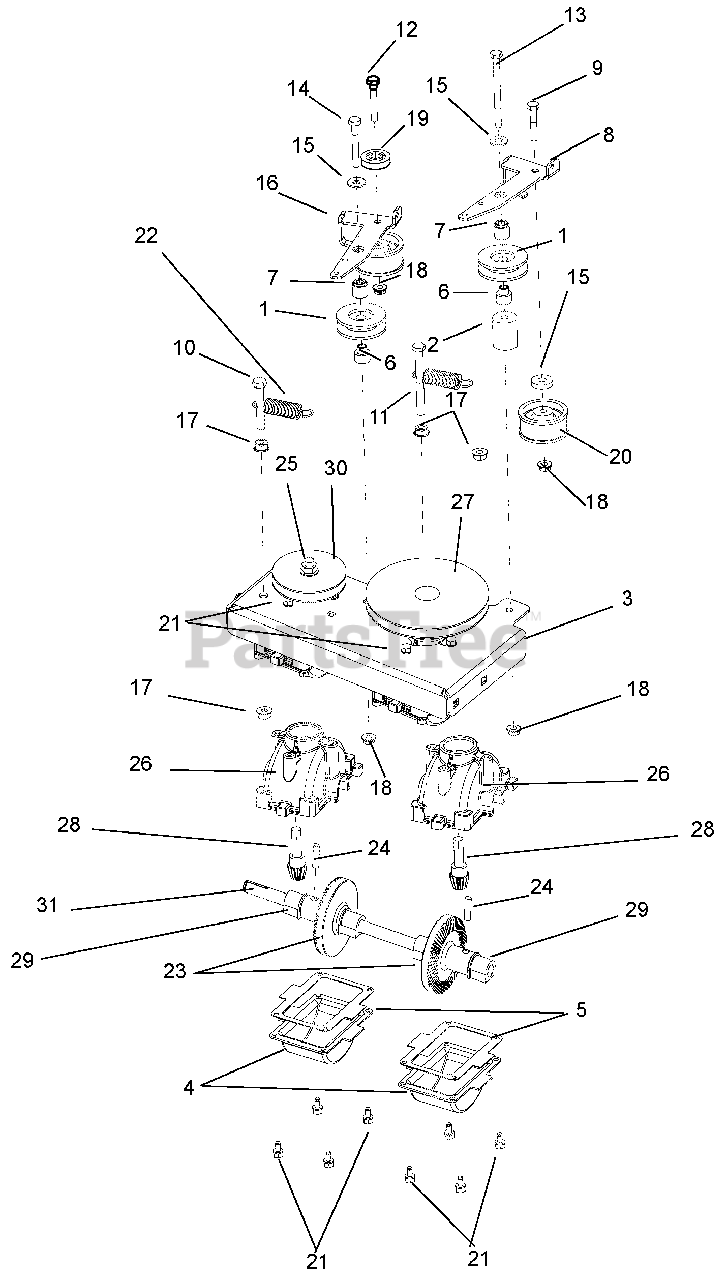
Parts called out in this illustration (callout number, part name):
1	IDLER, 3L FRONT SIDE .38X1.875
2	SPACER, REVERSE IDLER
3	PLATE-MOUNT, TRANS
4	SUMP, GEARBOX
5	GASKET, TRANSMISSION
6	SPACER, V-IDLER PULLEY
7	SPACER, IDLER ARM
8	BRKT-TRANS IDLER ARM
9	@BLT-HEX .25-20X1.50 GR5 YWZC
10	@BLT-HEX .31-18X2.00 GR5 YWZC
11	@BLT-HEX .31-18X3.50 GR5 YWZC
12	@BLT-HEX .25-20X1.75 GR5 YWZC
13	@BLT-HEX .25-20X3.25 YWZC
14	@BLT-HEX .25-20X2.00 GR5 YWZC
15	@WSHR-FL-STL.312X.734X.065 YWZ
16	WSHR-FL-STL .328X.87X.179 YWZC
17	@NUT-SPNLK-FLG .312-18 YWZC
18	@NUT-LK-TOP-FLG .25-20 YWZC
19	PULLEY, CABLE
20	PULLEY, ILDER .25X1.875X.97
21	SCR-TAP 10-24X.375 PRE-COAT 80
22	SPRG, TENSION .063X.625X2.50
23	GEAR, BEVEL (CU INFILTRATE)
24	PIN, .250 X 1.0 SPRING
25	@NUT-LK-TOP-FLG .38-16 YWZC
26	HOUSING, WBLM GEAR BOX
27	PULLEY, WAW REVERSE INPUT
28	PINION, GEARBOX INPUT
29	BUSHING, TRANS OUTPUT SHAFT
30	PULLEY, B.R. TRANS INPUT
31	KIT, WAW TRANS SHAFT SERVICE
32	KIT, WAW TRANSMISSION
